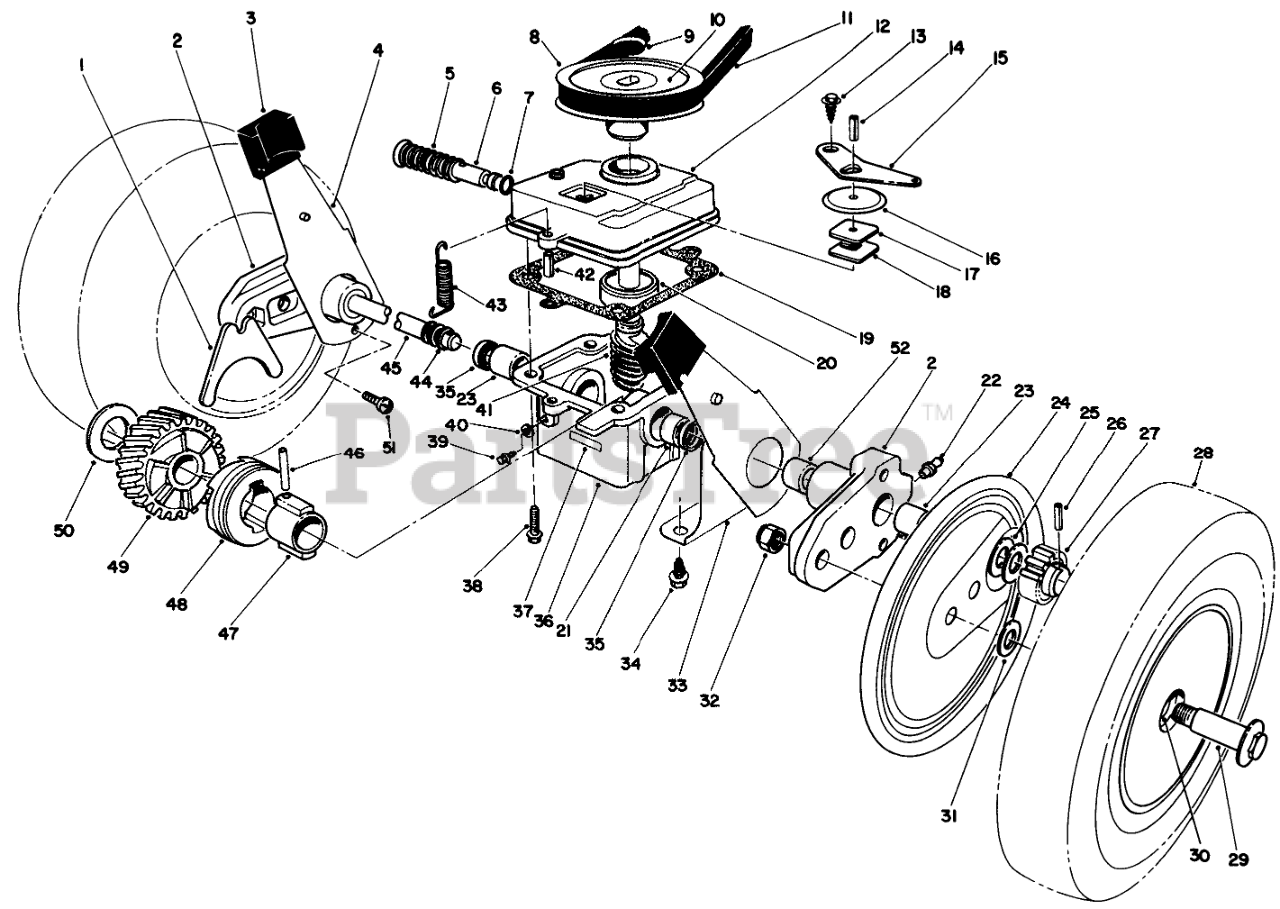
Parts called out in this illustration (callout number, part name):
1	SHIFTER FORK
2	Arm-Pivot (Incl. Ref. #22, 23, & 52)
3	KNOB-ARM
4	SPRING ARM ASSY-FRONT
5	SPRING
6	SHIFTER ROD
7	O-RING
8	PULLEY
9	PUSH-ON 93-3236
10	DECAL
11	V BELT
12	GEAR CASE COVER
13	Screw
14	SPIROL PIN H D
15	SHIFTER ARM
16	DUST COVER
17	DUST FILTER
18	LATCH PLATE
19	GASKET
20	BEARING
21	BUSHING
22	FITTING-GREASE
23	BUSHING
24	WHEEL COVER
25	THRUST WASHER
26	Pin
27	PINION GEAR 15T
28	Wheel, Tire, & Gear Assembly (Incl. Ref. #30)
29	BOLT-WHEEL
30	BUSHING
31	WASHER
32	Nut
33	END CAP
34	SCREW-HWHTF
35	SEAL-OIL
36	Gear Case (Incl. Ref. #21, 23, & 35)
37	DECAL
38	Screw
39	NYLON SCREW
40	FILL PLUG GASKET
41	Worm Shaft & Gear (Incl. Ref. #49)
42	3/16 X 1/2 ROLL PIN
43	TENSION SPRING
44	COVER-SHAFT, DRIVE
45	DRIVE SHAFT
46	COIL PIN
47	SLEEVE
48	CLUTCH JAW
49	Helical Gear
50	THRUST WASHER
51	SCREW
52	BUSHING
